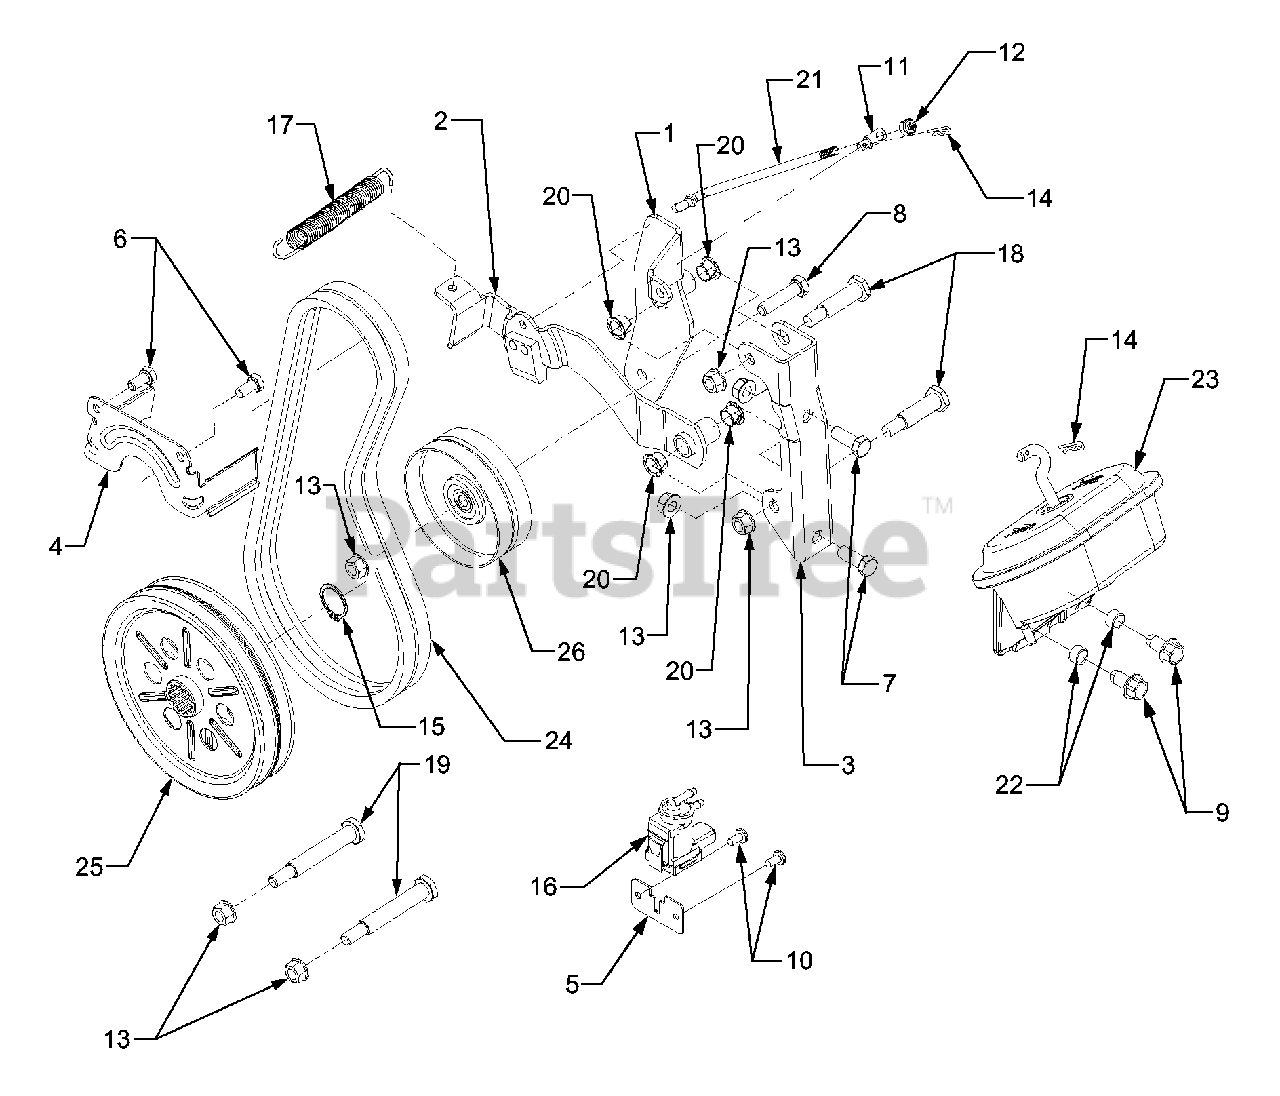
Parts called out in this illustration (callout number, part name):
1	Bracket, Idler
2	Bracket Assembly, Brake
3	Bracket, PTO Mounting
5	Bracket, Solenoid Mounting
6	Screw, Hex Cap 5/16-24 x .625 GR5
7	Screw, Hex Cap 3/8-16 x 1.0 GR5
8	Screw, Hex Cap 3/8-16 x 1.5 GR5
9	Screw, Hex Wash. Hd. Tapp 3/8-16 x .75
10	Screw, Phil. Hd. Tapp #12-14 x .5
11	Ferrule, Brake Adjustment
12	Nut, Hex Insert Lock, 1/4-20
13	Nut, Flange Lock, 3/8-16
14	Pin, Internal Cotter
15	Snap Ring, 1.0 Dia Shaft
16	Solenoid, Kit Vacuum Actuator
17	Spring, Extension, .530 x 4.74
18	Shoulder Screw, .498 x 1.45
19	Shoulder Screw
20	Bearing, Nylon Flange
21	Rod, PTO Brake
22	Spacer, .380 x .5 x .265
23	Vacuum Actuator
24	V-Belt, A-Section x 37.63 (Set of two belts)
25	Pulley, PTO Drive. 6.75-Double
26	Pulley, Flat Idler, 4.0
